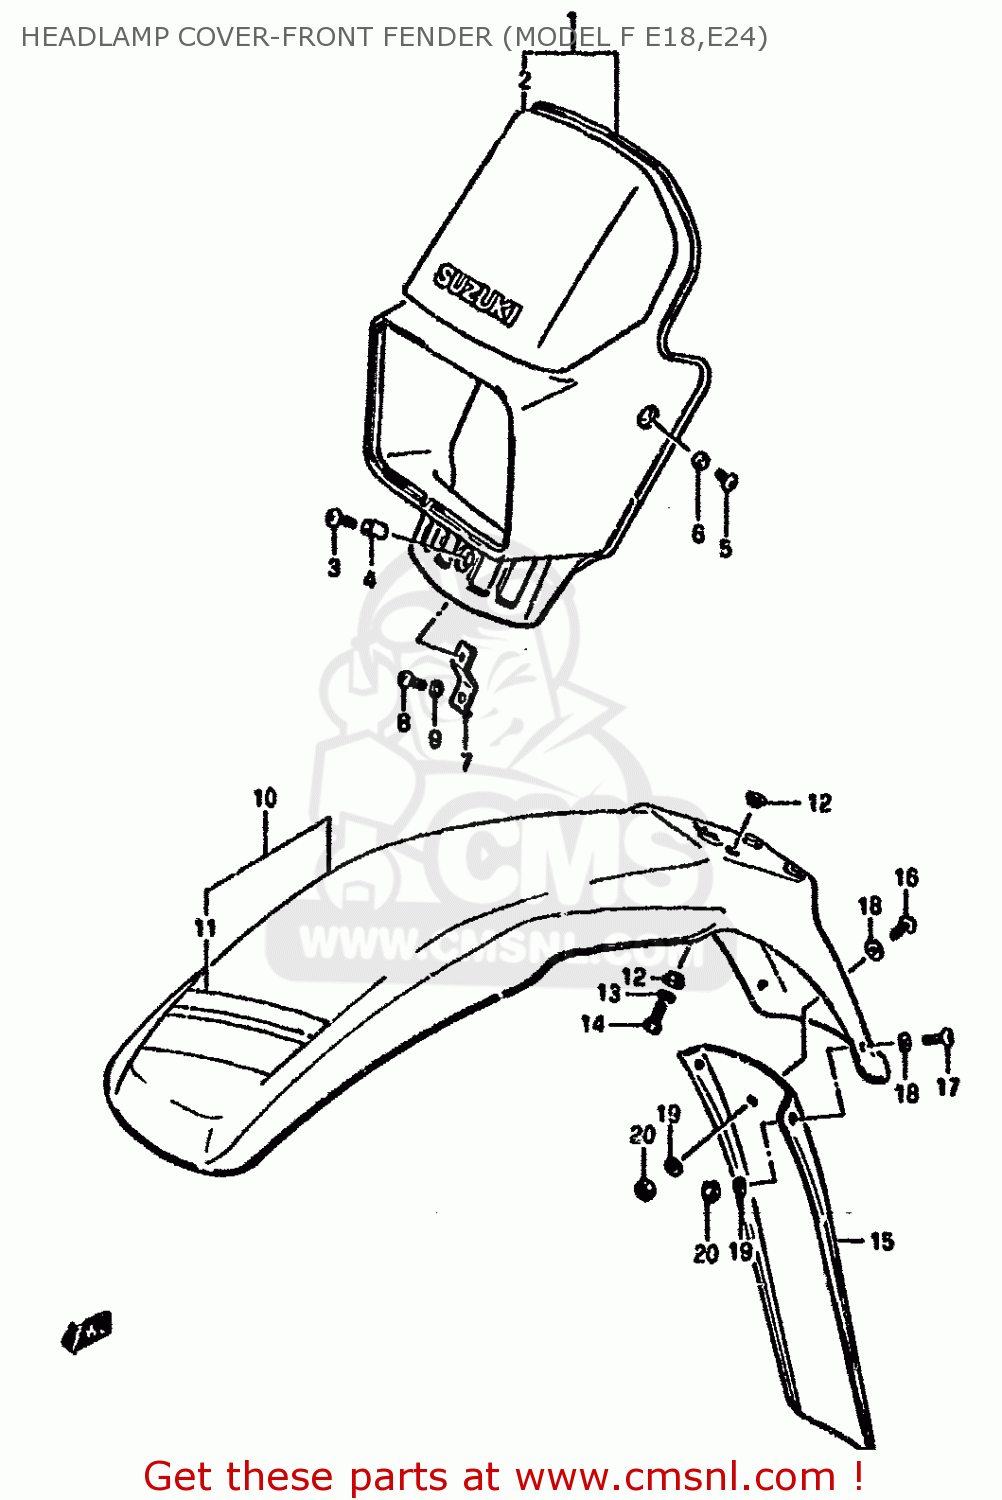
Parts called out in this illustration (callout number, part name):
1	COVER,HEADLAMP
2	TAPE SET
3	SCREW, CENTER
4	SPACER (6.1X8X12)
5	SCREW 6X12
6	SPACER (6.1X8X3.5)
7	BRACE,HEADLAMP HOUSING LWR
8	SCREW 6X12
9	WASHER,LOCK
10	FENDER,FRONT (BLUE)
11	TAPE SET
12	SPACER
13	WASHER,LOCK
14	BOLT, UPPER
15	MUD FLAP
16	SCREW, CENTER
17	SCREW
18	WASHER (6.7X16X1.8)
19	WASHER,LOCK
20	NUT 6MM
